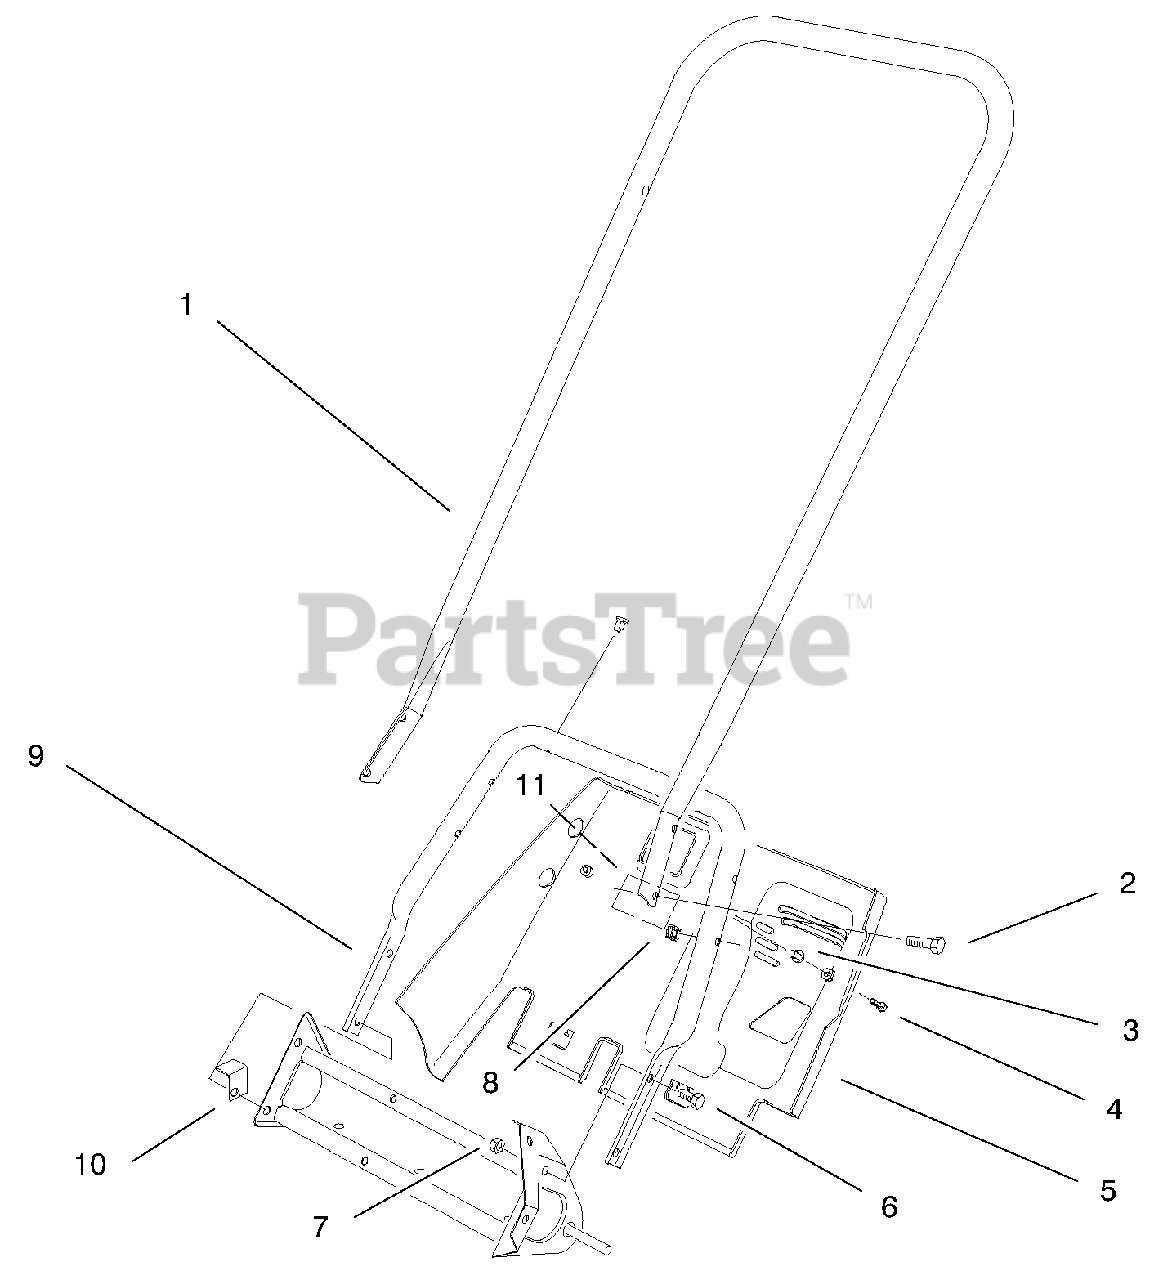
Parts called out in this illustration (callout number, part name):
1	Handle-Upper
2	Screw-Hex. Hd.
4	Screw-Thread Forming
5	Shroud-Lower
6	Screw-Hex. Hd.
7	Nut-Lock
8	Nut-Speed
9	Handle-Lower
10	Bracket-Shroud
11	Decal-Warning CSA
